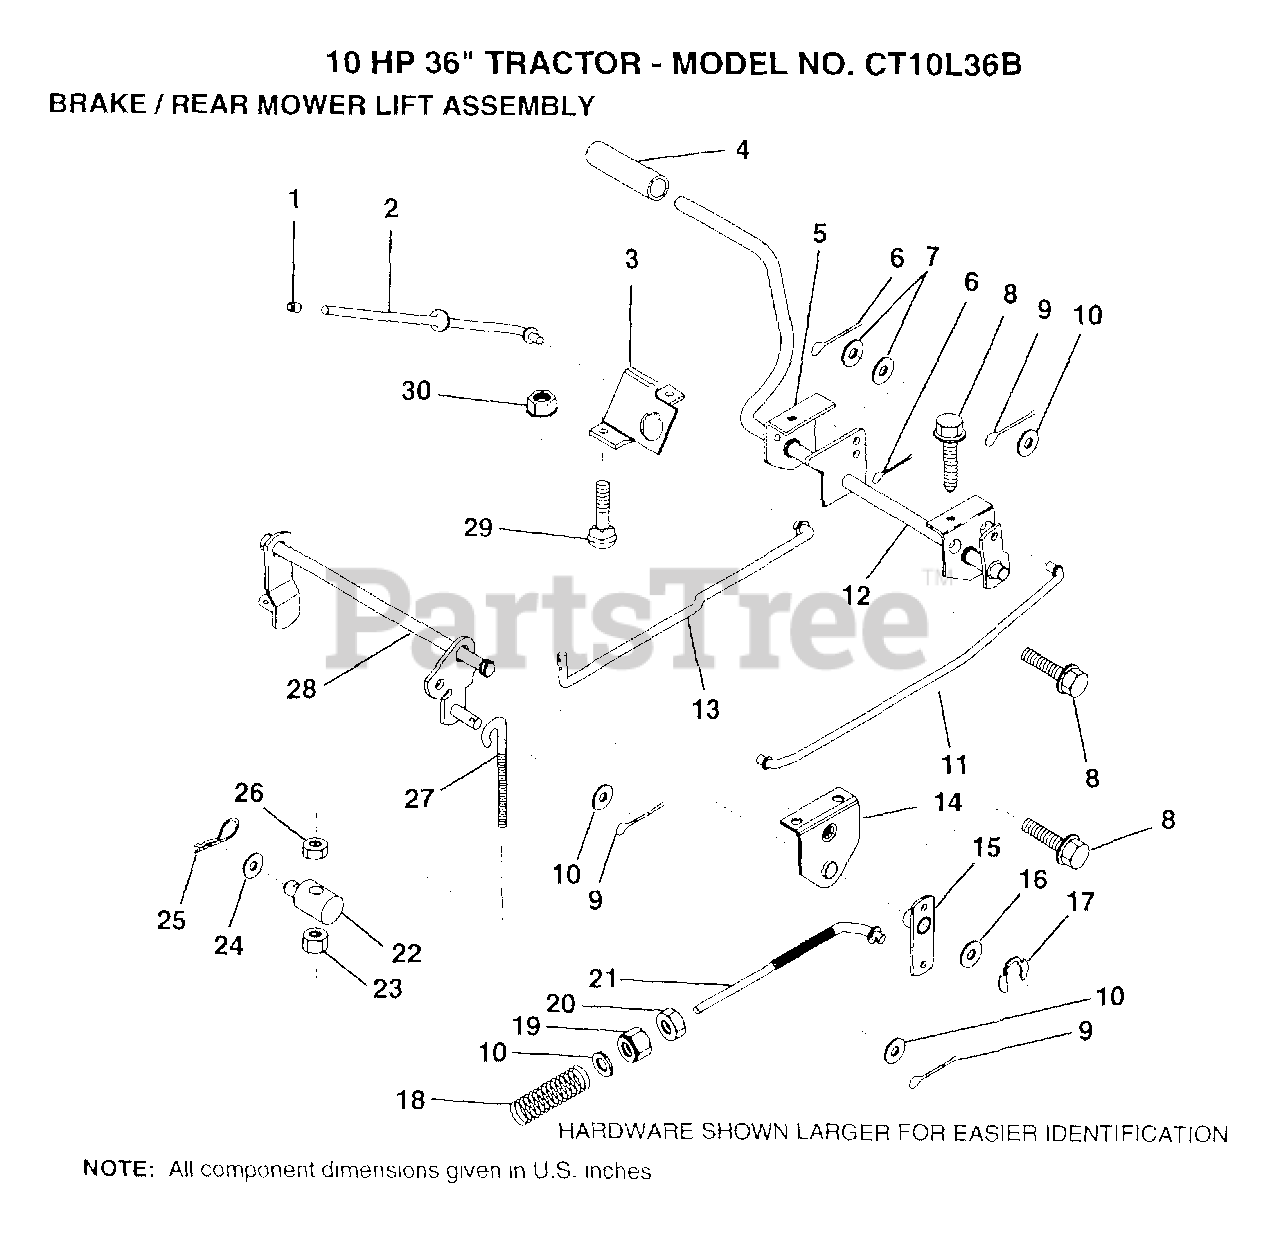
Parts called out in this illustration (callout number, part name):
1	PLUNGER CAP T
2	"ROD,PARK BRAKE"
3	"BRKT,PARK BRAKE"
4	FOOT PEDAL COVER
5	"BRKT,CLU PEDAL LH"
7	WASHER
8	SCREW LT
9	COTTER PIN
10	WASHER
11	"ROD,FRT BRAKE"
13	"ROD,CLUTCH"
14	"BRKT,LIFT SHAFT"
15	BRAKE PIVOT ARM
16	WASHER T
17	KLIP RING
18	SPRING ROD LT
20	NUT
24	WASHER
25	SPRING.RETAINER
26	LOCKNUT
27	"LINK, MOWER REAR"
